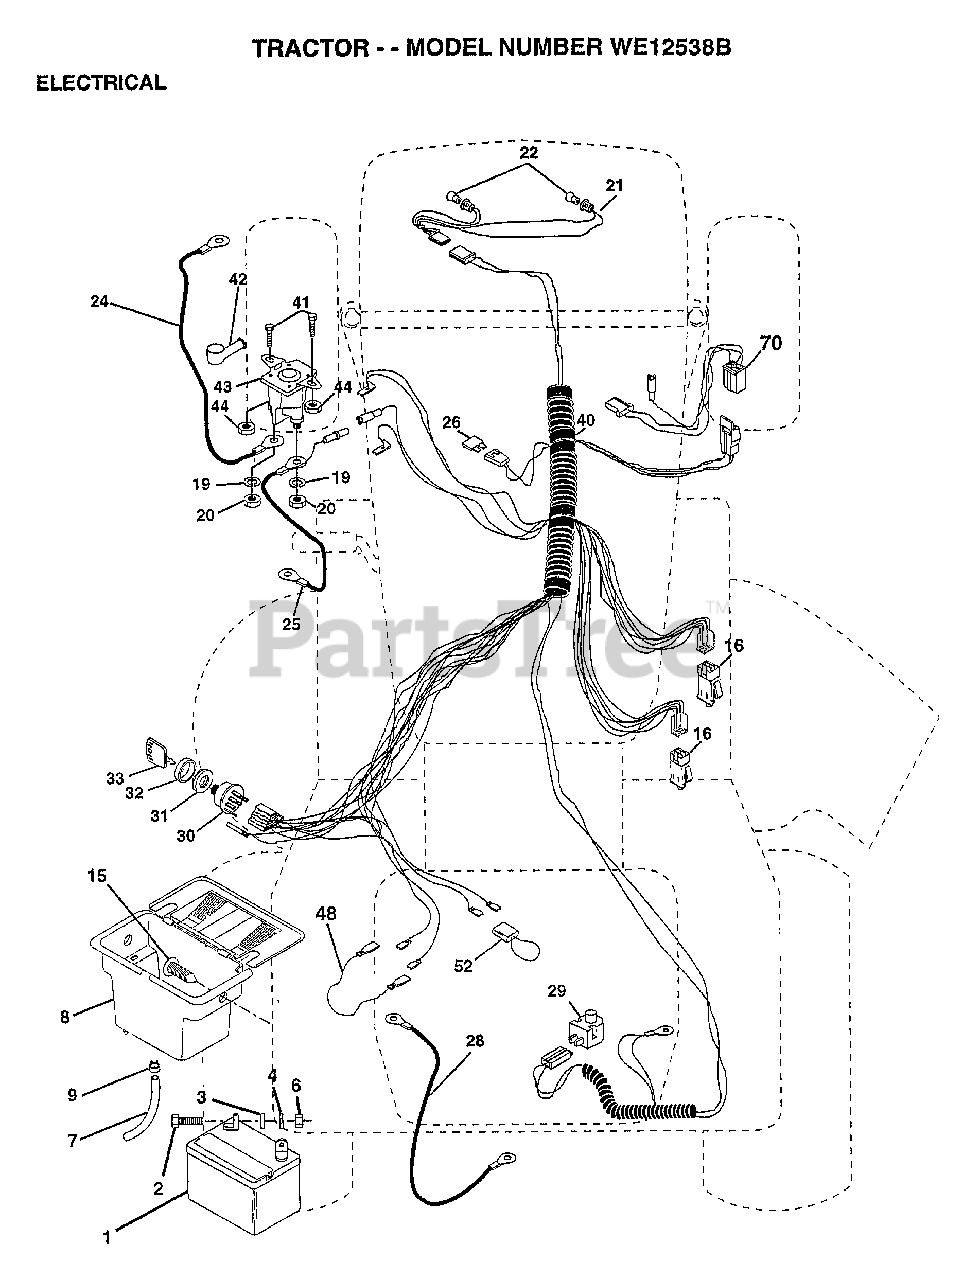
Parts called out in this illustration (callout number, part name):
2	BOLT LT
3	WASHER
4	LOCKWASHER
7	TUBE T
8	"CASE,BATTERY.MECH"
9	HOSE CLAMP T
15	FASTNER.SNAP-IN
16	SWITCH INTERLOCK
20	NUT
21	"HARNESS,LIGHT SOC"
22	HEADLAMP BULB
24	"CABLE T, BATTERY"
25	CABLE.BTRY.6GA.RD
26	FUSE HYT
28	CABLE T
29	SWITCH SEAT
30	SWITCH IGN 4POS
31	NUT IGNITION
32	COVER KEY SWITCH
33	KEY
40	HARNESS-IGNITION
41	BOLT HXHD FIN
44	NUT HXKEP 1/4X20
48	ADAPTER AMMETER
52	PROTECTION LOOP
70	HARNESS ENG DUAL
